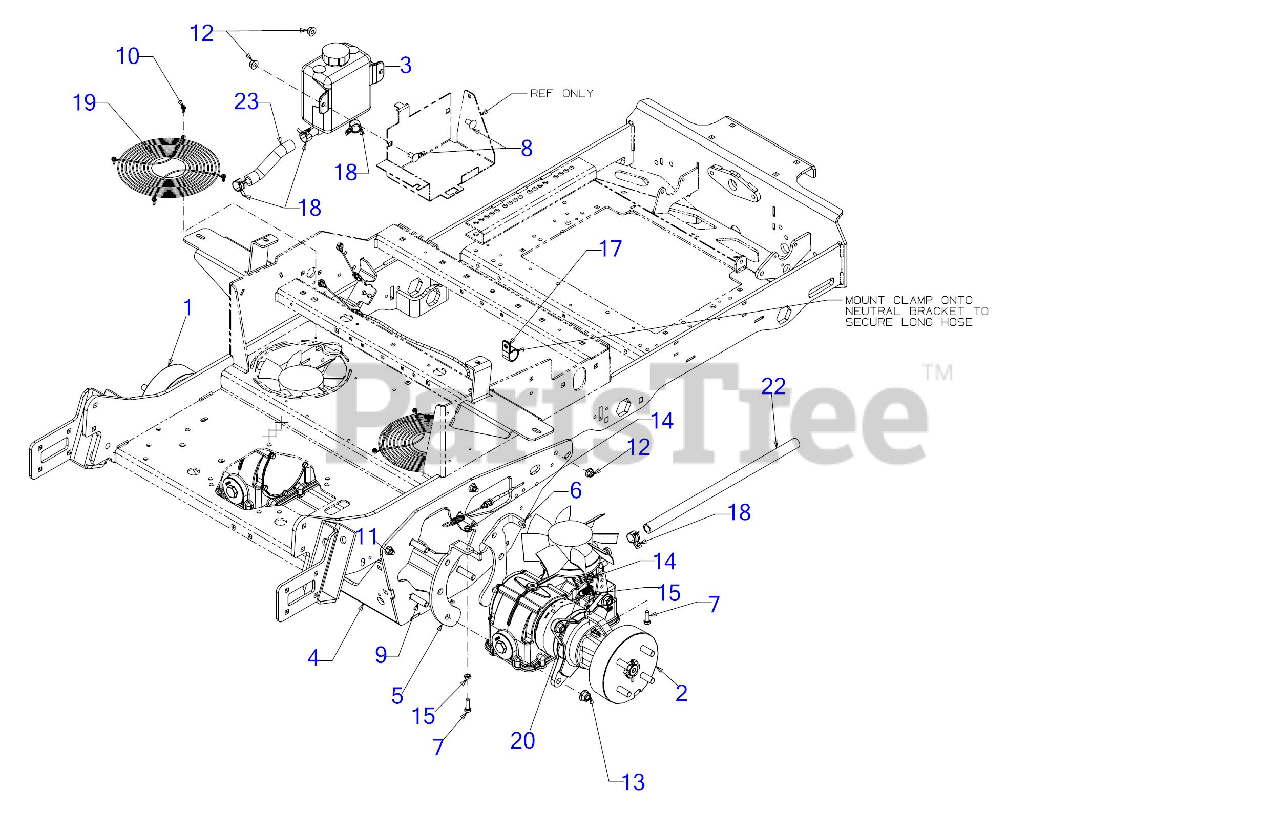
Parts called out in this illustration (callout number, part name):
1	TRANSMISSION ASSEMBLY PARKER (LH)
2	TRANSMISSION ASSEMBLY PARKER (RH)
3	HYDRO TANK ASSEMBLY
7	SCREW 5/16-18 x 1.0 GR5
8	CARRIAGE BOLT 3/8-16 x .750 GR5
9	CARRIAGE BOLT 1/2-13 GR5
10	SCREW 10-24 x 0.500
11	CARRIAGE BOLT 3/8-16 X1.25 GR5
14	HEX FLANGE NUT
17	HOSE CLAMP 1.0"
18	HOSE CLAMP
20	EXTENSION SPRING .500 OD x 1.71
22	OIL HOSE 5/8 ID X 18.00 LG
